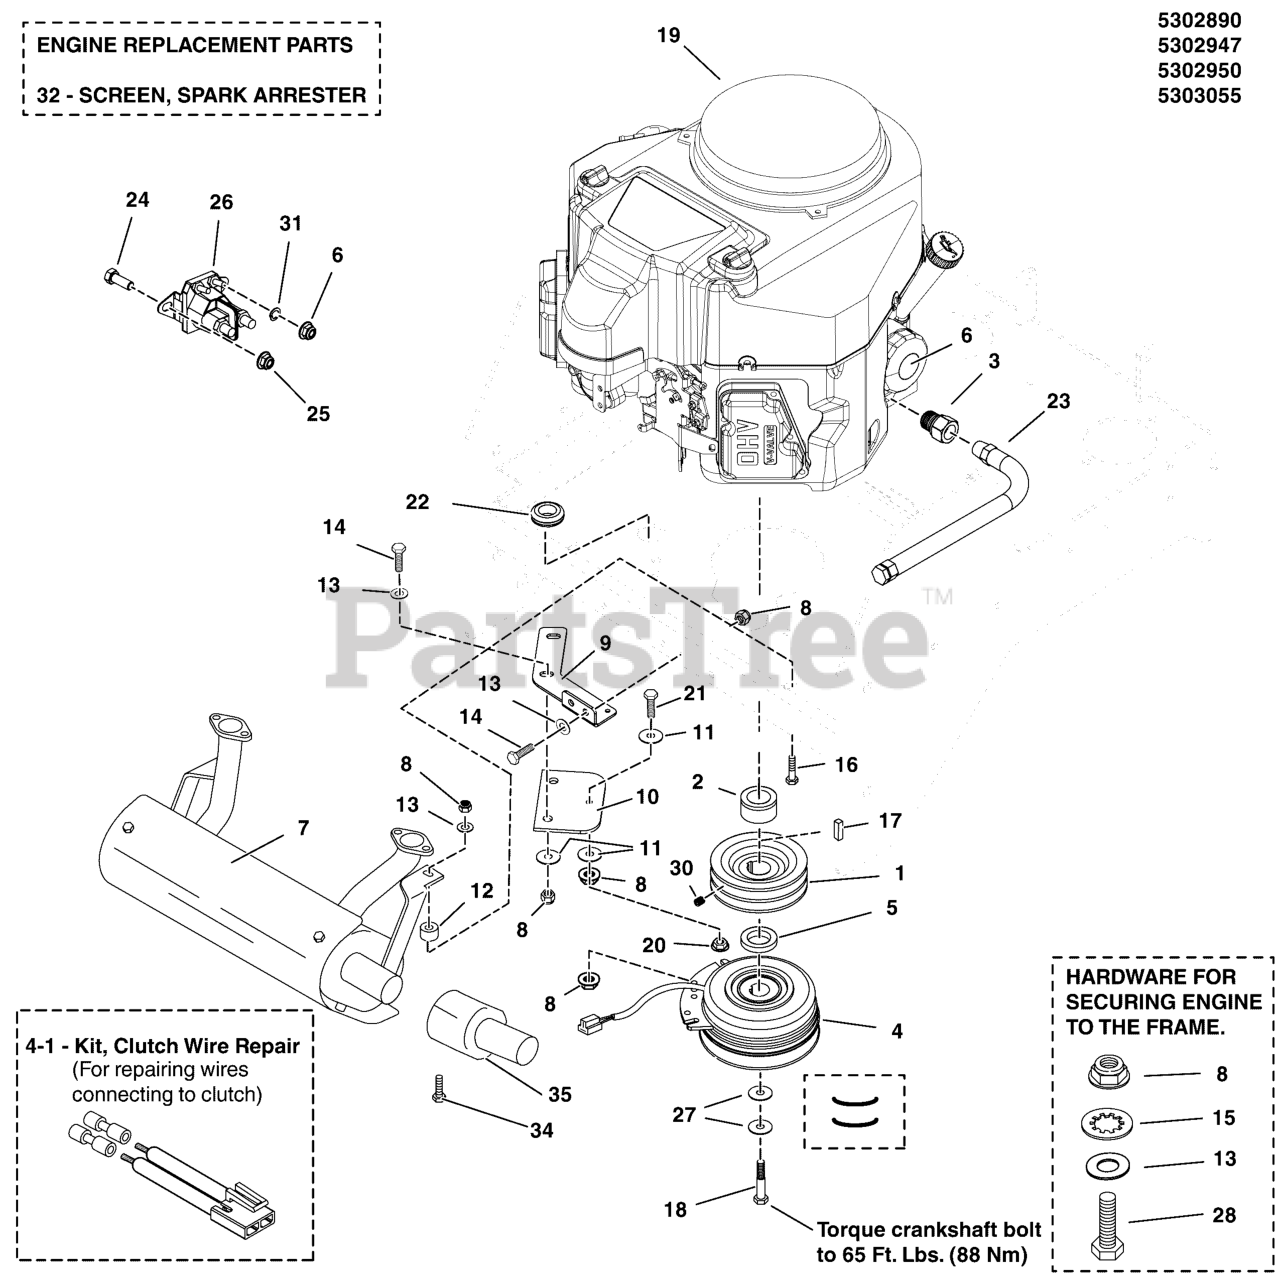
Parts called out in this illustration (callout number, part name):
1	PULLEY, CRANKSHAFT, 1.126 ID X 4.75 OD
2	SPACER, 1.13 X 1.75 X 1.03, CZ
3	ADAPTER, Oil Drain
4	CLUTCH WARNER 200 FT-LB 1.13 X 6.323
4-1	KIT, CLUTCH WIRE REPAIR
5	SPACER, 1.13 X 1.75 X .375
6	NUT, Hex Jam, 5/16-24
7	MUFFLER, KAWI, HORIZONTAL, 5" CAN
8	NUT, 5/16-18 HEX NYLOCK FLANGE NUT
9	PLATE, CLUTCH ANCHOR
10	CLUTCH ANCHOR PAD
11	WASHER, .34 X 1.25 X 10 GA
12	SPACER, .39 X 1.00 X .80, CZ
13	WASHER, 5/16" SAE
14	BOLT, 5/16-18 X 1" GRD5 YZ
15	WASHER, 5/16" Internal Tooth Lock
16	BOLT, 5/16-18 X 1-3/4" GD5 YZ
17	KEY, 1/4 SQ X 1
18	BOLT, CRANKSHAFT,7/16-20X2-1/2, GD8
19	ENGINE, KAWASAKI
20	NUT, 5/16-18 HEX SERRATED FLANGE (LARGE)
21	BOLT, 5/16-18 X 2-1/2 GD5 TFL, CZ
22	GROMMET, 7/8"
23	HOSE, OIL DRAIN
24	BOLT, 1/4"-20 X 3/4" GD5 YZ
25	NUT, 1/4-20 HEX SERR. FLANGE
26	SOLENOID-4 POLE 12 VOLT DC (TROMBETTA)
27	BELLEVILLE WASHER, 1.1875 X .442 X .098
28	BOLT, HEX FLG, SER, GD5 3/8-16 X 1-1/4" PACH CZ
29	NUT, HEX, M8-1.25, CZ, GD 8.8
30	SET SCREW, 5/16-18 X 3/8, KNURL, W/PATCH
31	WASHER, Light Lock, 5/16
32	SCREEN, SPARK ARRESTER (SV)
33	TIE,SELF-LOCKING, 24"
34	SCREW, SELF-TAP, #8-32 X 3/8. WASH HEX, CZ
35	EXTENSION, TAILPIPE, 3" - BLACK
